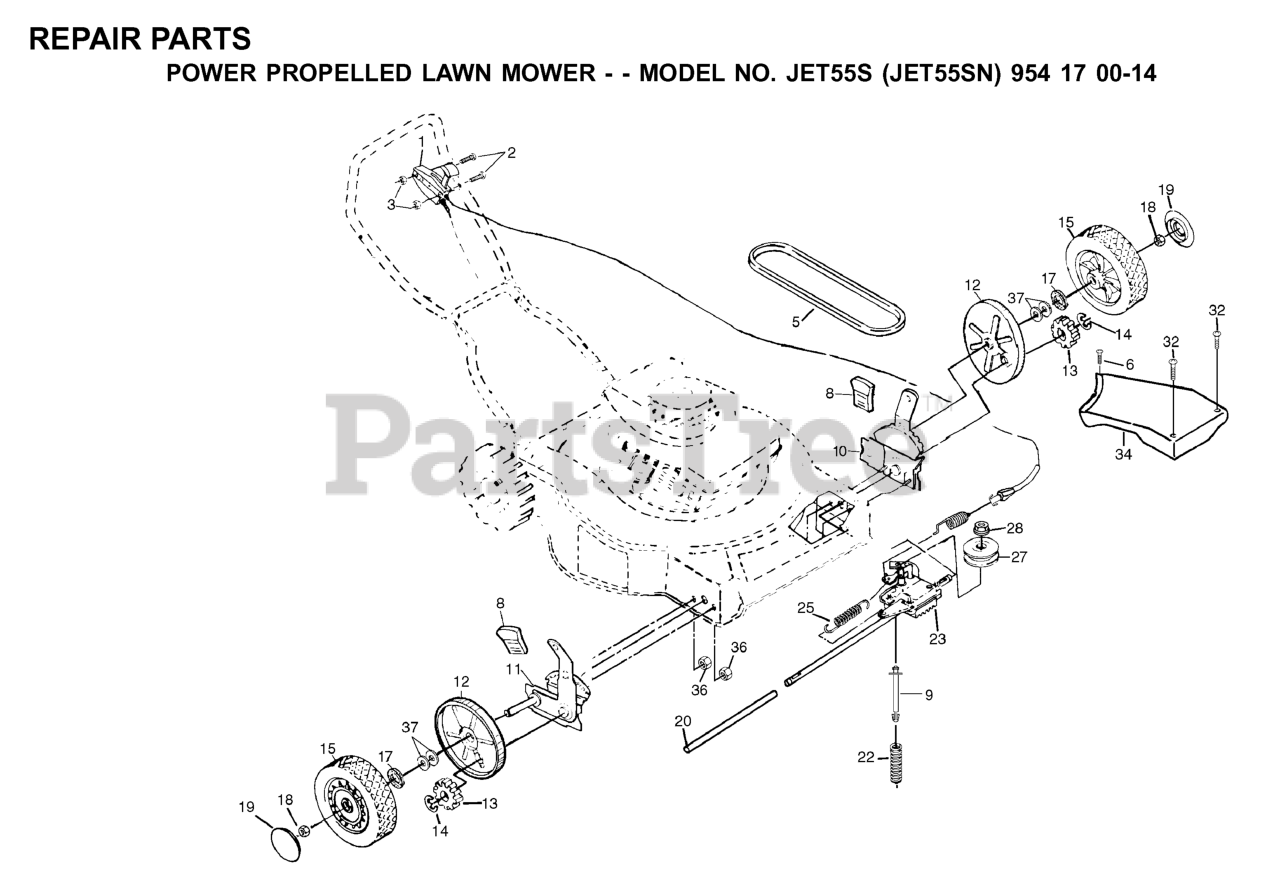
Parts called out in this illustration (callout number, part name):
2	SCREW 1/4-20 X 2.12
3	NUT
5	BELT THERM .32
6	TAPPING SCREW
8	SELECTOR KNOB
9	SPRING RETAINER
10	WHEEL ADJUSTER ASSY (LEFT)
11	WHEEL ADJUSTER KIT RH
12	DUST SHROUD PM
13	PINION GEAR
14	E-RING 7/16 RE
15	WHEEL & TIRE 8 X 2
17	WASHER FLUT
18	HEX FLANGE LOCKNT
19	HUBCAP.8".GREY
20	DRV SHAFT TUBE PM
22	SPRING.EXTENSION
23	GEAR CASE ASMBLY
27	PULLEY
28	FLANGED LOCKNUT 3/8-16 ZINC
34	COVER DRIVE
36	NUT
37	WAVE WASHER
